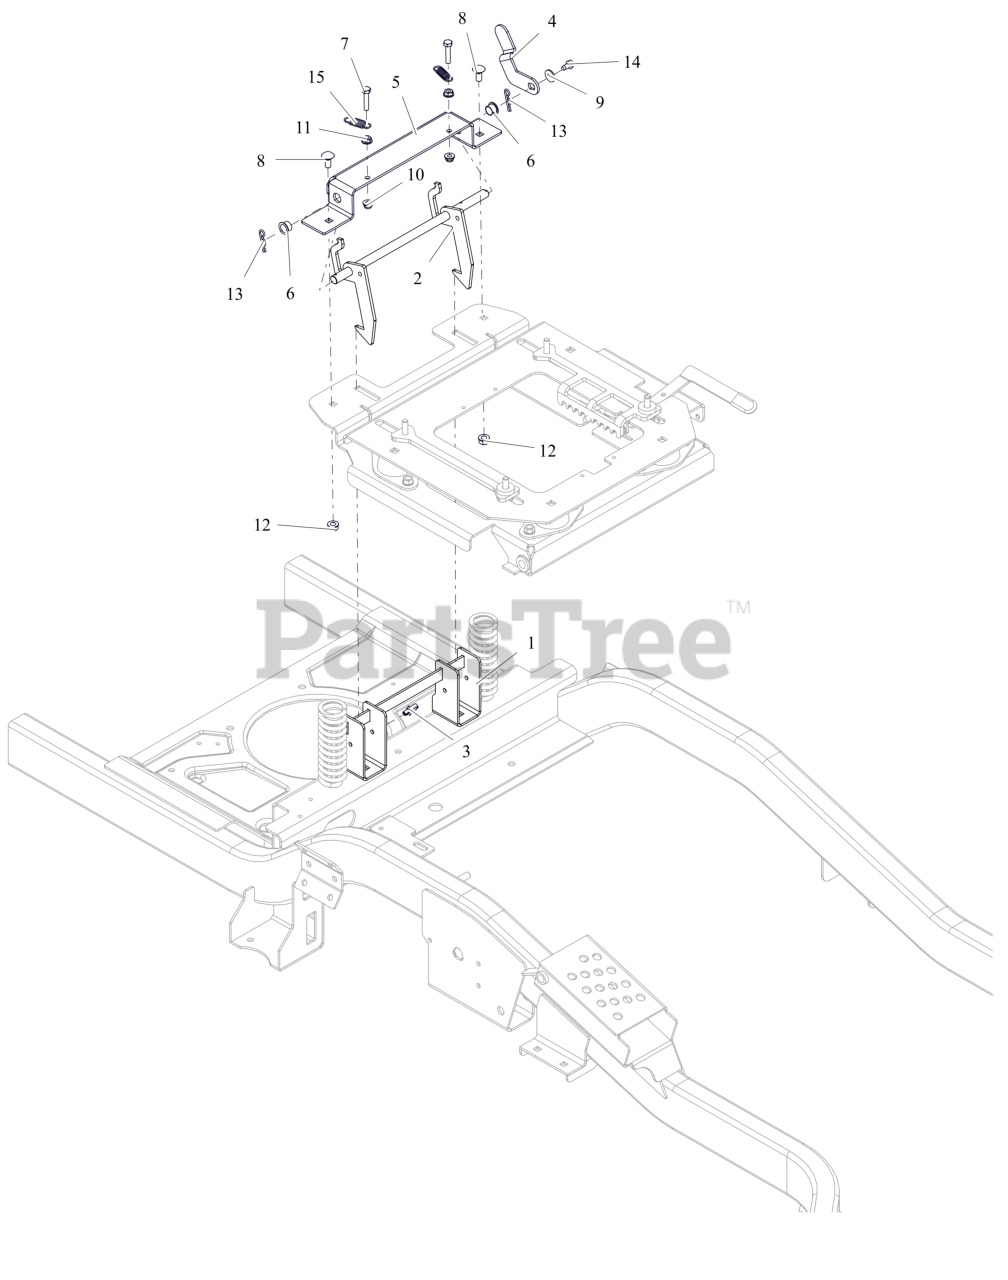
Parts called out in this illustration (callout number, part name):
1	WLDMT, LATCH RECEIVER
2	WLDMT, SEAT LATCH
3	ROUTING CLIP (1/2" ID)
4	LEVER, SEAT LATCH RELEASE
5	BRKT, SEAT HOOK MTG.
6	BUSHING, POLYLINER-.50 SPLIT
7	BLT, HEX .25-20X1.25 G5 ZCC
8	BLT,RHSN .31-18X.75 G5 ZCC
9	WSHR, FLT .312X.734X.065 ZCC
10	NUT,NYL-FLG .25-20 GF ZCC
11	NUT-SPNLK-FLG .25-20 ZC120
12	NUT,LK-CTR-FLG .31-18 GF ZCC
13	PIN, HAIR .08X.38X1.42 ZCC
14	SCR-TAP .25-20X.50 HWH ZCC
15	SG-TENS .063X.44X1.56
